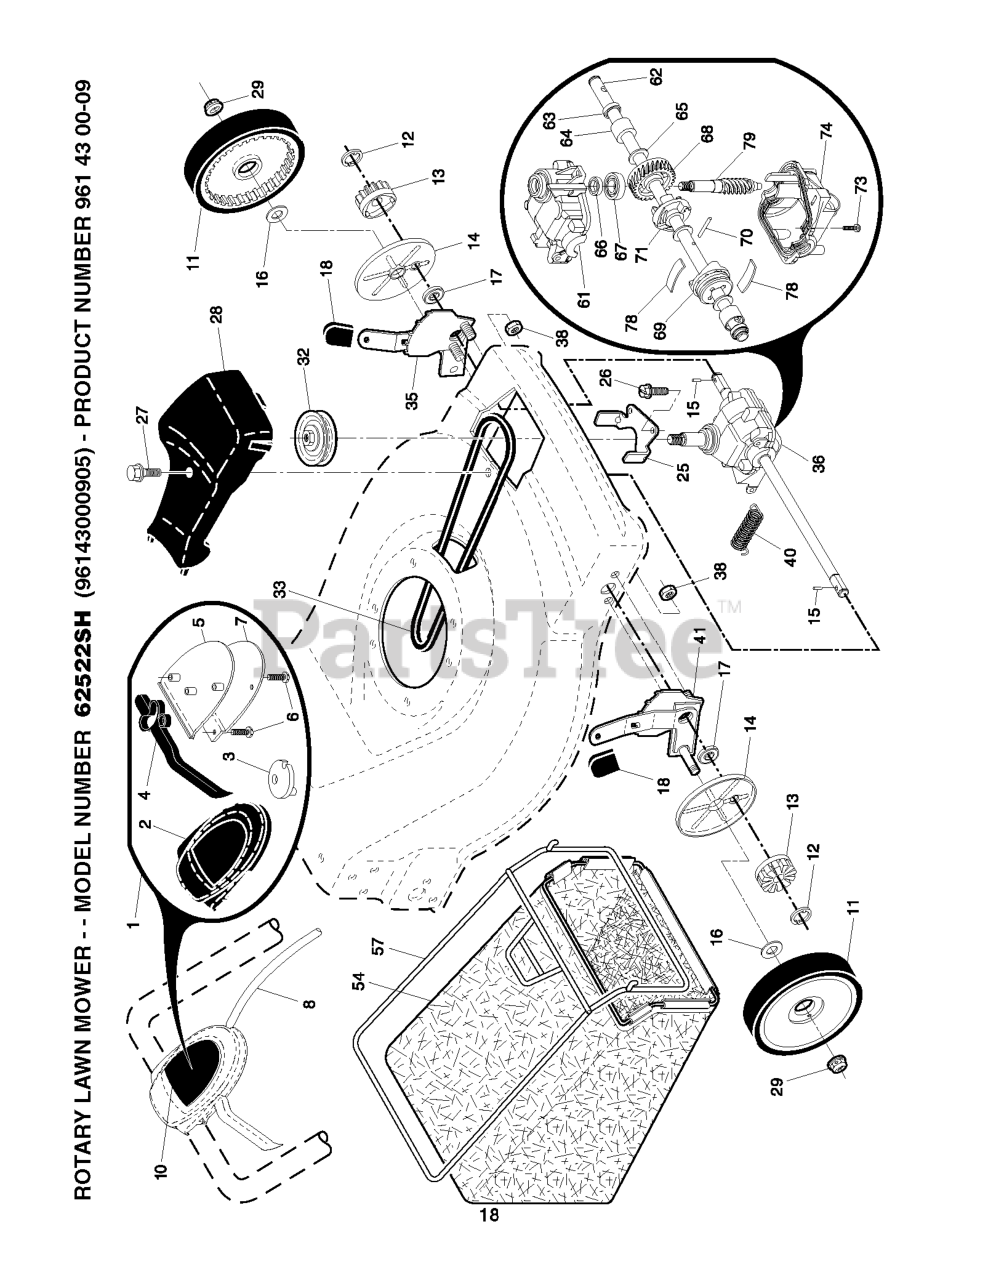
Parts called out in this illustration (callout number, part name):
1	DRIVE CONTROL ASSEMBLY (INCLUD
2	COVER TOP AUTO WALK CONTROL
3	PULLEY
4	LEVER, AUTOWALK DRIVE CONTROL
5	COVER BOTTOM AUTO WLK CONTROL
6	SCREW, PHILLIPS HEAD 10 X 5/8
7	BRACKET.DRIVE.CONTROL.MOUNT.BL
8	CABLE ASSEMBLY, DRIVE
10	DECAL, DRIVE
11	WHEEL.8X1.75.H3SPK.RAD3.GY.BU3
12	E-RING 7/16 RE
13	PINION.14.TEETH.FGD
14	COVER.DUST.WHEEL
15	PAWL.DRIVE
16	WASHER FLUT
17	BEARING
18	KNOB.DELUXE.GRAY
25	BELT KEEPER
27	SCREW, HEX HD TAPPING #10-24 1
28	RP DRIVE COVER
29	NUT.HEX.FLANGE.3/8-16.LO(3 2)
32	RP PULLEY.DRIVE.EZ
33	BELT.DRIVE.FG
35	WHEEL ADJ KIT LH
36	TRANSMISSION.22.VS.FWGD
38	LOCKNUT.NYLOC.1/4-20
41	WHEEL ADJ KIT RH
54	GBAG.8471024T.SIL.HUSQ.BLU
57	FRAME GRASSBAG
61	CASE.UPPER.00254(SERVICE)
62	Shaft, Output
63	SEAL.OUTPUT.SHAFT
66	SEAL INPUT SHAFT
68	GEAR 28 TEETH 36208
69	FIXED DOG CLUTCH
70	PIN.3.50.33733
71	MOVEABLE DOG CLUTCH
74	CASE.BOTTOM.
78	SPRING LEAF
79	SHAFT WORM
